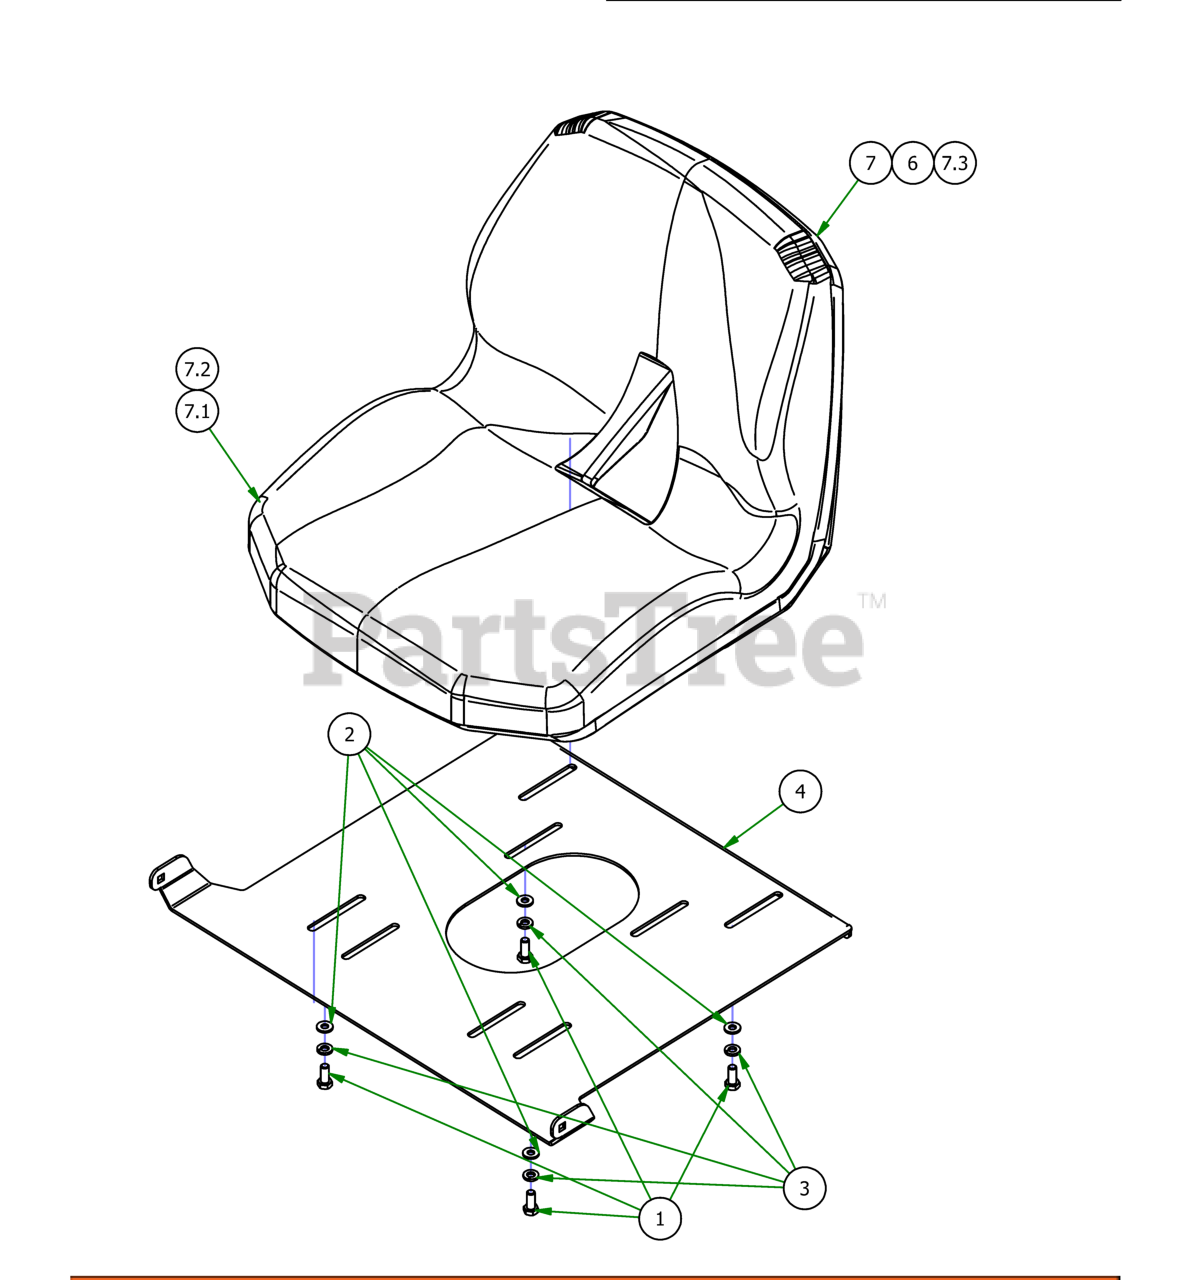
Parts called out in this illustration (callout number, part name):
1	5/16" x 3/4" Hex Bolt
2	1/4" Flat Washer
3	5/16" Lock Washer
4	2017 MZ Seat Plate
6	2019 42" MZ Seat
7	2019 Magnum Seat/Kohler
7.1	Seat Cover for 071-1000-00
7.2	Seat Foam for 071-1000-00
7.3	2014 Magnum Seat Switch
